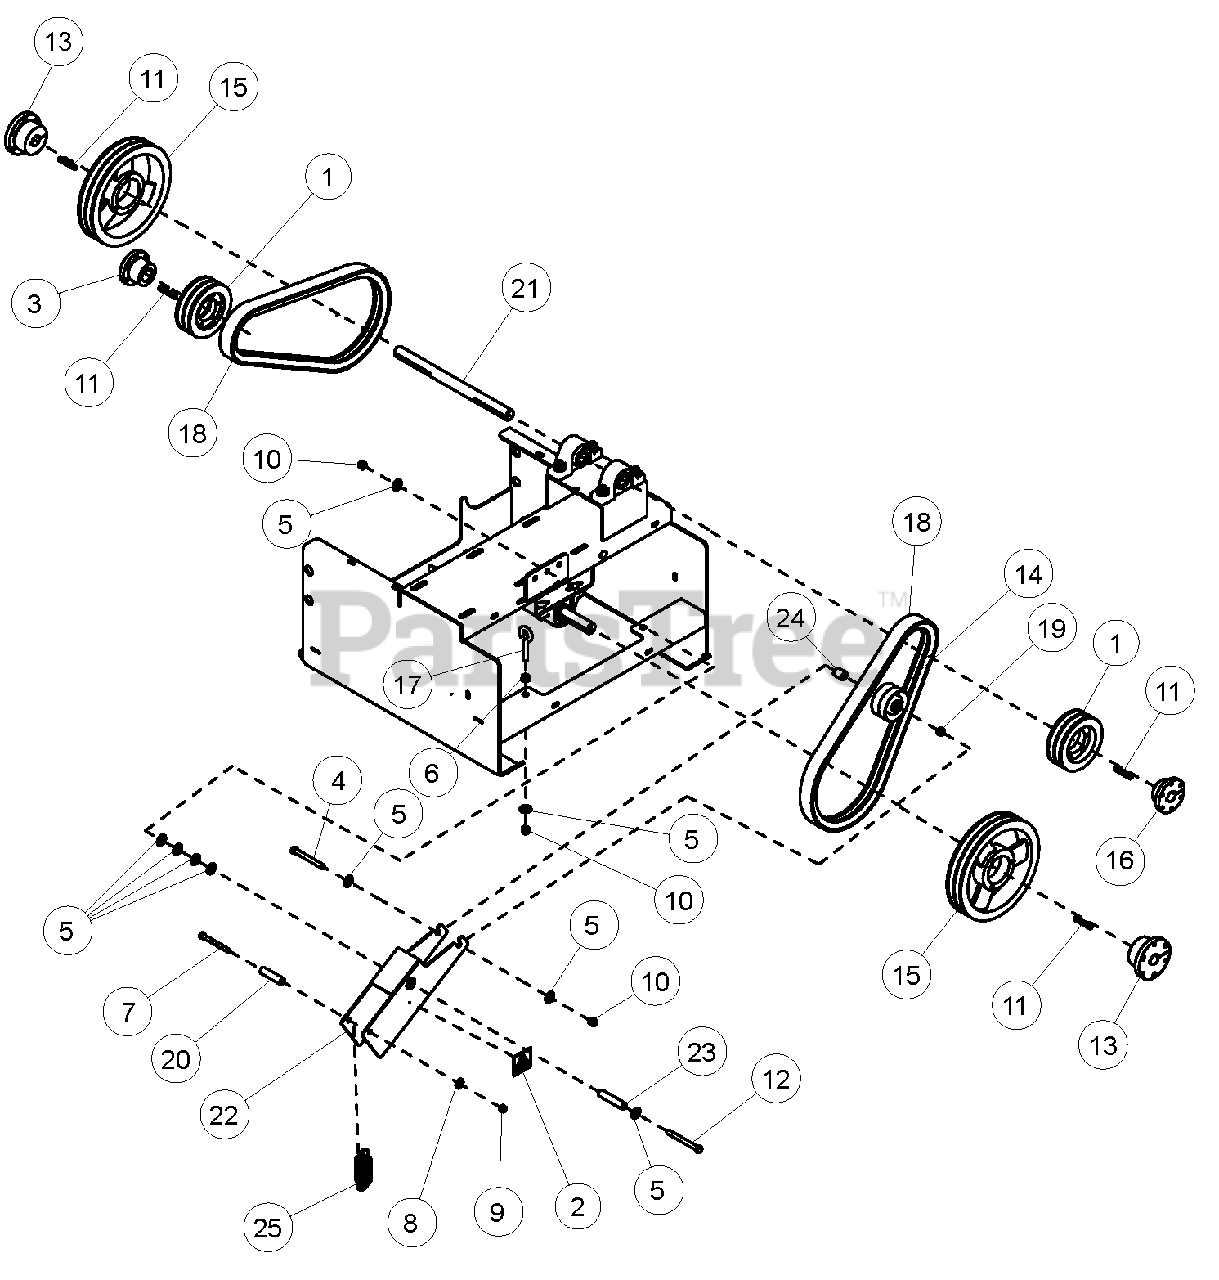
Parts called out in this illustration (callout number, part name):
1	SHEAVE, 2B4.8 SDS
2	DECAL, SHIELD DANGER
3	BUSHING, 1-1/4" SDS
4	BOLT, 3/8 NC X 3-1/2 HEX HD
5	WASHER, 3/8" FLAT
6	NUT, 3/8" SERR FLANGE
7	BOLT, 5/16 X 3-1/4" HEX HD
8	WASHER, 5/16" FLAT
9	NUT, 5/16" NYLOCK
10	NUT, 3/8" NYLOCK
11	KEY, 1/4 X 2" SQ.
12	BOLT, 3/8 NC X 3-3/4" HEX HD GR5
13	BUSHING, 1 SK
14	PULLEY, 3-1/4" FLAT IDLER
15	SHEAVE, 2B9.4 SK
16	BUSHING, 1.0 SDS
17	BOLT, 3/8 X 2" EYE
18	BELT, 2RB47
19	TUBE, SPACER
20	GUIDE, BELT
21	JACKSHAFT, CHIPPER
22	WELDMENT, IDLER
23	SPACER, 0.63 X 2.880
24	SPACER, 0.75 X 0.90
25	STOCK EXTENSION SPRING
